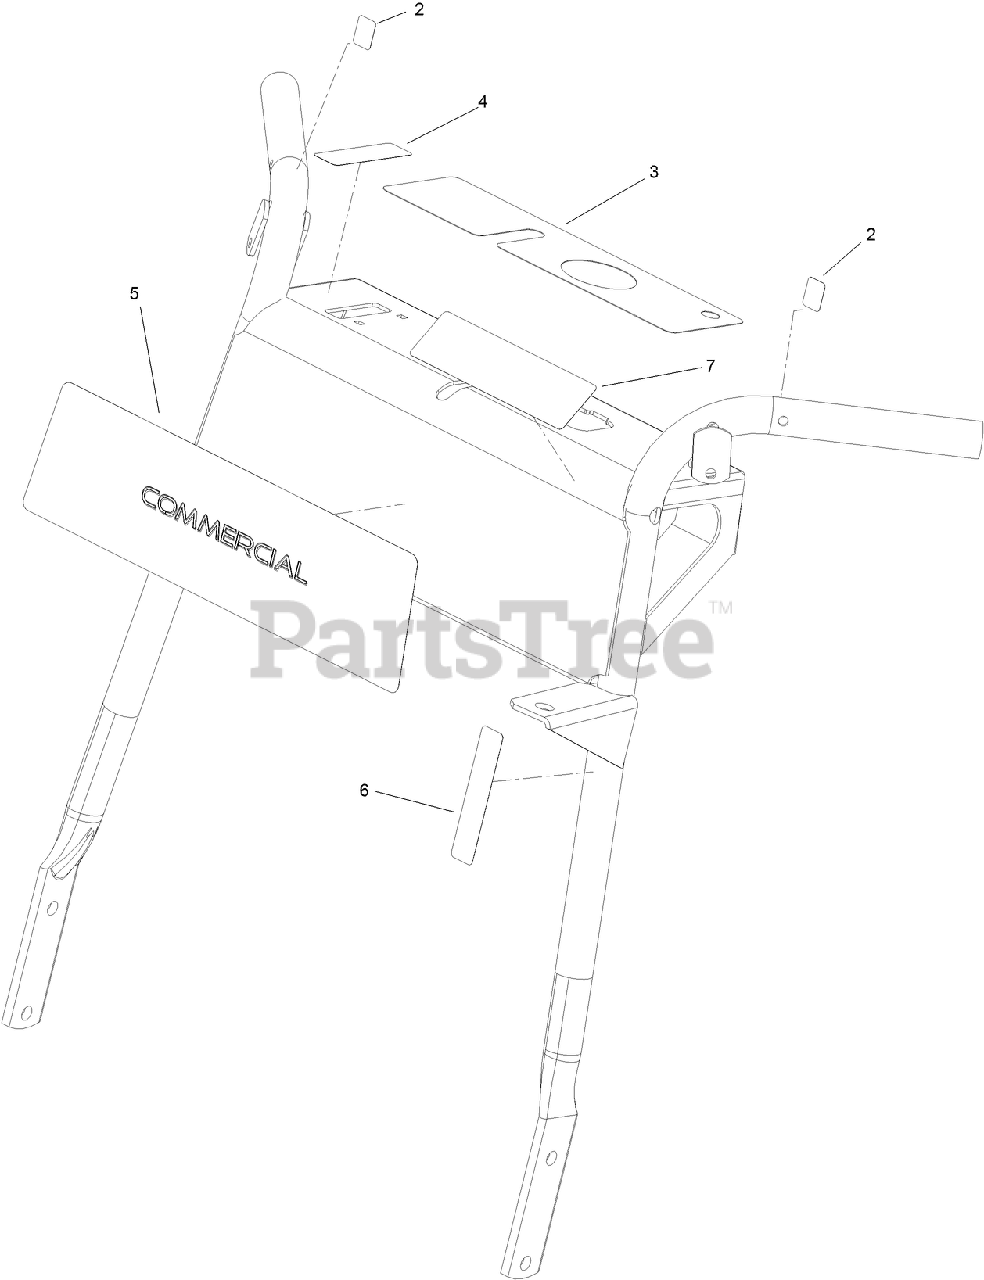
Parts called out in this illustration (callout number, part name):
2	DECAL-LOCK,NEUTRAL
3	DECAL-CONTROL PANEL
4	DECAL-THROTTLE
6	DECAL-ENGAGE, DECK
7	DECAL - SLOPE, INT'L
